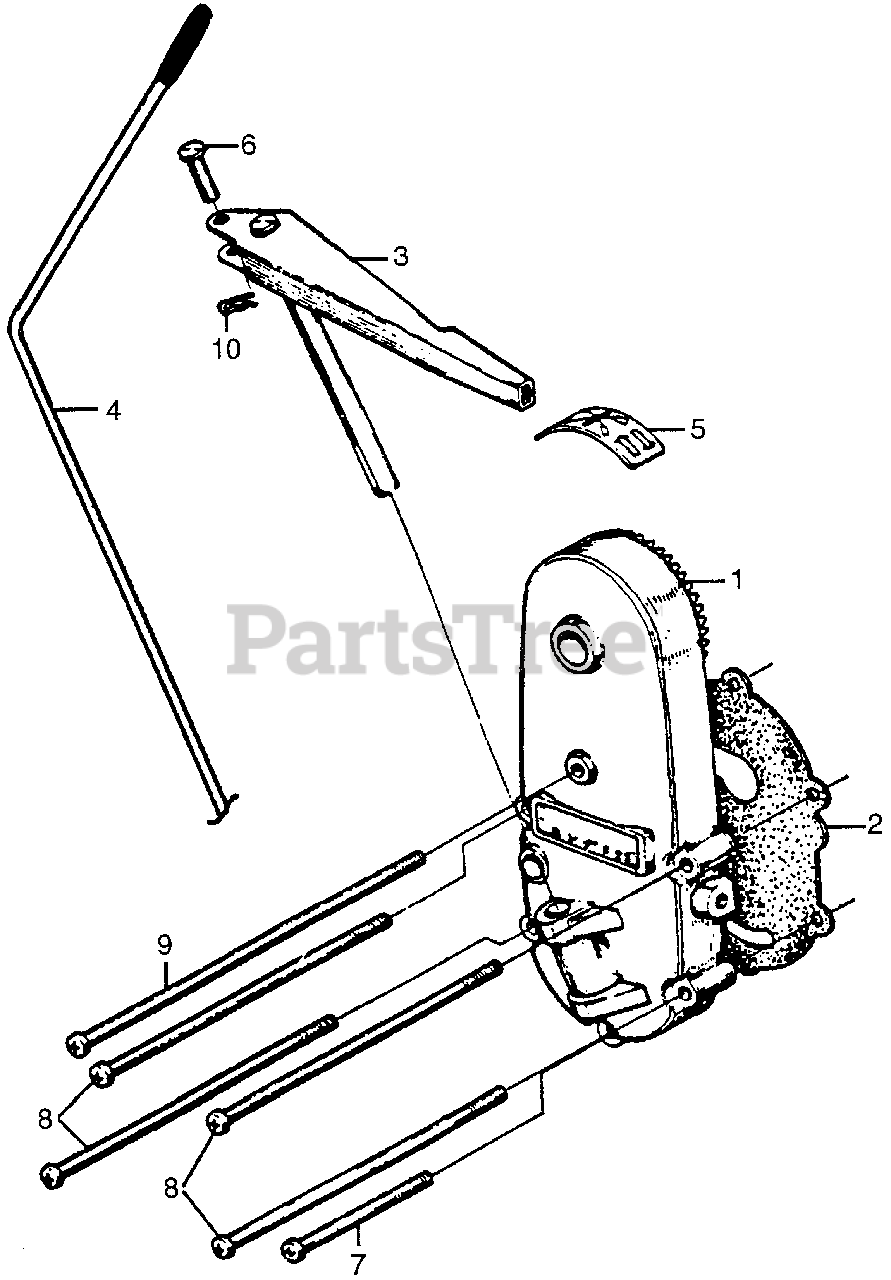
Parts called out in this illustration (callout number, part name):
1	COVER, L. SIDE (NOT AVAILABLE)
2	GASKET, L. SIDE
3	HANDLE, CHANGE (NOT AVAILABLE)
5	MARK, INDICATION (NOT AVAILABLE)
6	PIN (4X19)
7	SCREW, PAN (6X40)
8	SCREW, PAN (6X90) (SOURCE: VINTAGE PARTS INC.)
9	SCREW, PAN (6X112) (NOT AVAILABLE)
10	PIN, LOCK (4MM)
